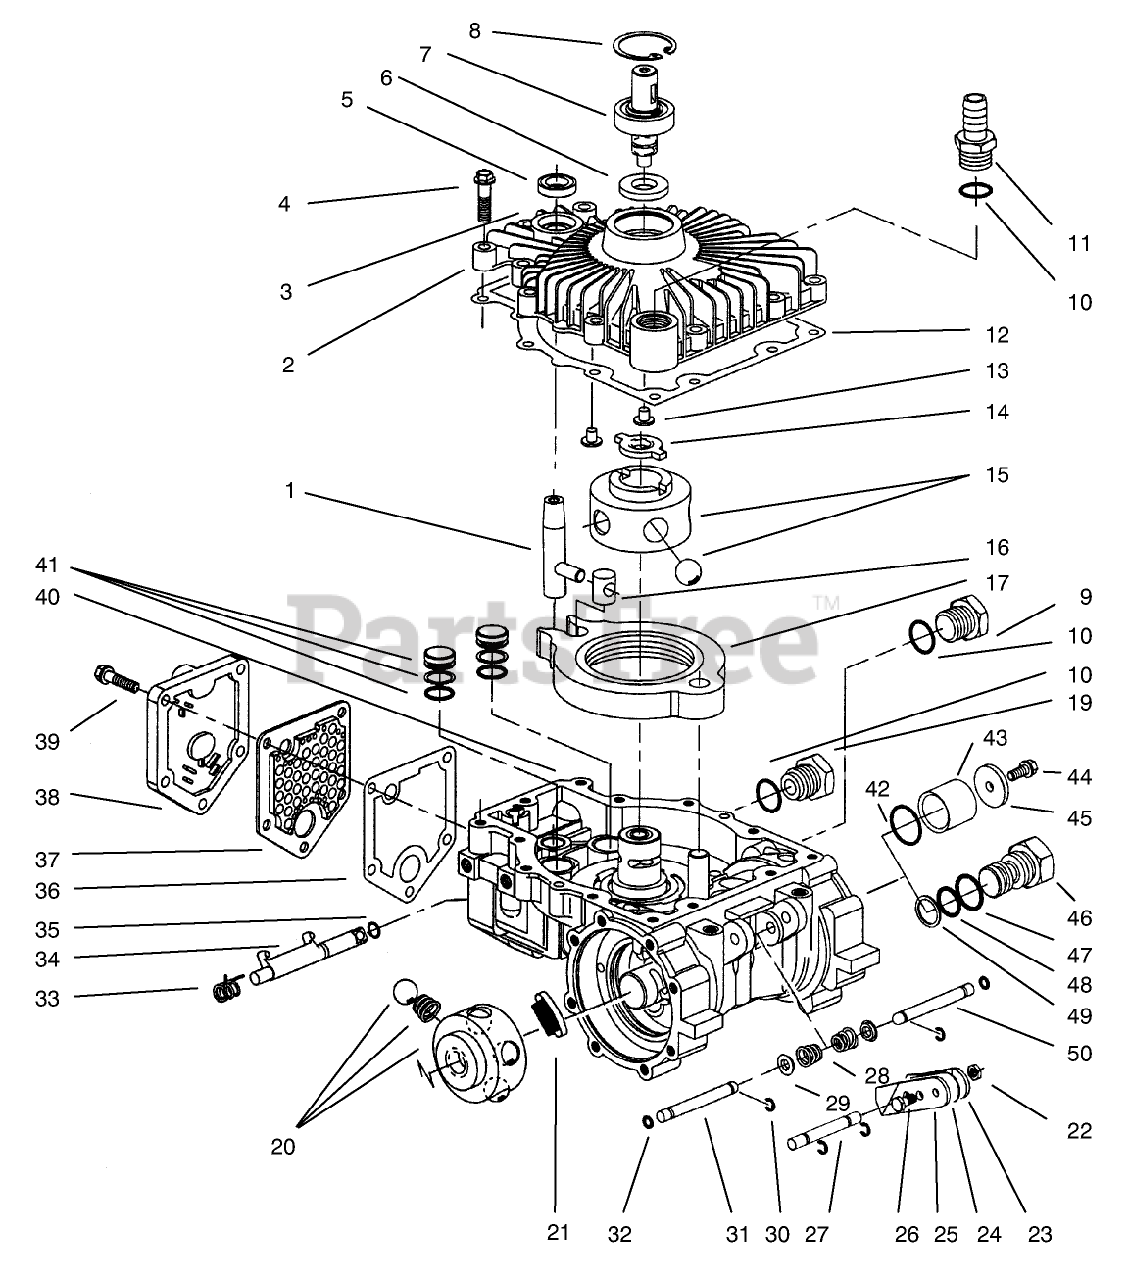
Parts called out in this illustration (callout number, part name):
1	CONTROL SHAFT
2	COVER ASM
3	COVER
5	SEAL-OIL
10	O-RING
17	CAM RING ASM
19	ROTOR BALL ASM
20	ROTOR BALL ASM
25	LH BRAKE LEVER
26	HEX HEAD SCREW
27	BRAKE SHAFT
31	PUSH ROD
32	QUAD SEAL
34	DUMP VALVE BRACKET
39	1/4-20 HEX HEAD SCREW
41	PISTON ASM
42	O-RING
43	CUP SEAL
45	WASHER
47	O-RING
48	O-RING
49	BACKUP RING
50	PUSH ROD
